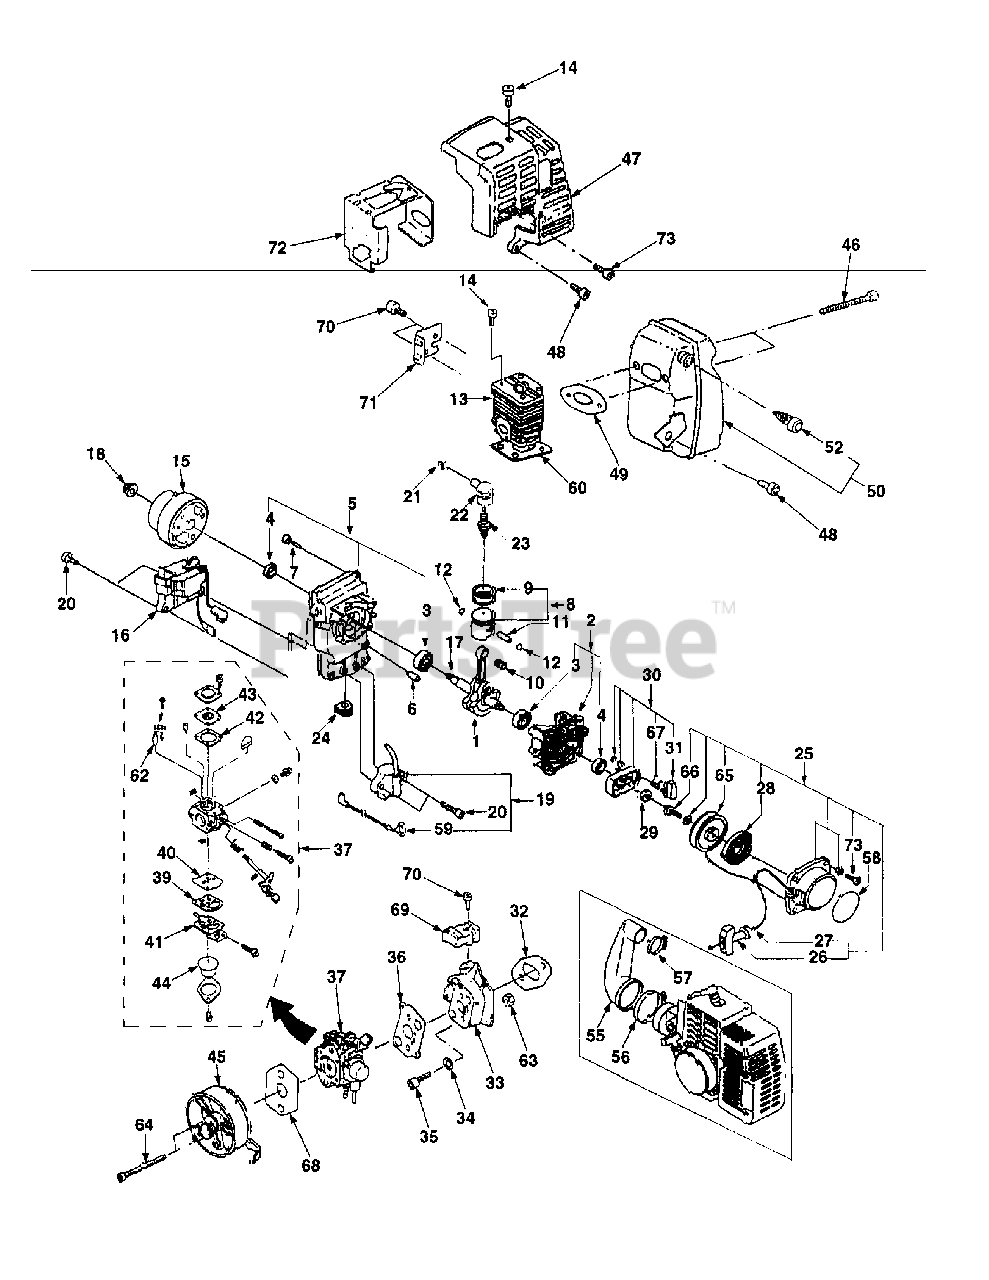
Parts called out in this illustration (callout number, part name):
1	Crankshaft
2	Crankcase Ass'y
3	Ball Bearing; 6202
4	Oil Seal
5	Crankcase Ass'y
6	Dowel Pin
7	Bolt; M5x30
8	Piston Ass'y
9	Ring, Piston
10	Needle, Bearing
11	Pin, Piston
12	Clip, Piston Pin
13	Cylinder
14	Bolt; M5x16
15	Flywheel, Magneto
16	CDI Unit
19	Coil Ass'y, Ignition
20	Bolt; M4x16
22	Cap, Plug
23	Plug, Spark
25	Recoil Ass'y
26	Knob, Starter
27	Rope, Starter
28	Spring, Spiral
30	Pulley, Starter
32	Gasket, Insulator
33	Insulator
34	Washer
35	Bolt; M5X25
36	Gasket, Carburetor
37	Carburetor Ass'y
40	Diaphragm, Pump
41	Body, Pump
43	Diaphragm, Pump
45	Case Compl
46	Bolt; M5x58
48	Bolt; M5x12
49	Gasket, Muffler
52	Arrester
55	Elbow, Intake
58	Trade Mark
59	Harness, Wire
60	Gasket, Cylinder
62	Valve, Float
64	Bolt; M5x50
67	Spring, Return
68	Gasket, Air Silencer
69	Adjuster
70	Bolt, M4x12
71	Plate, Baffle
73	Bolt, M5x20
